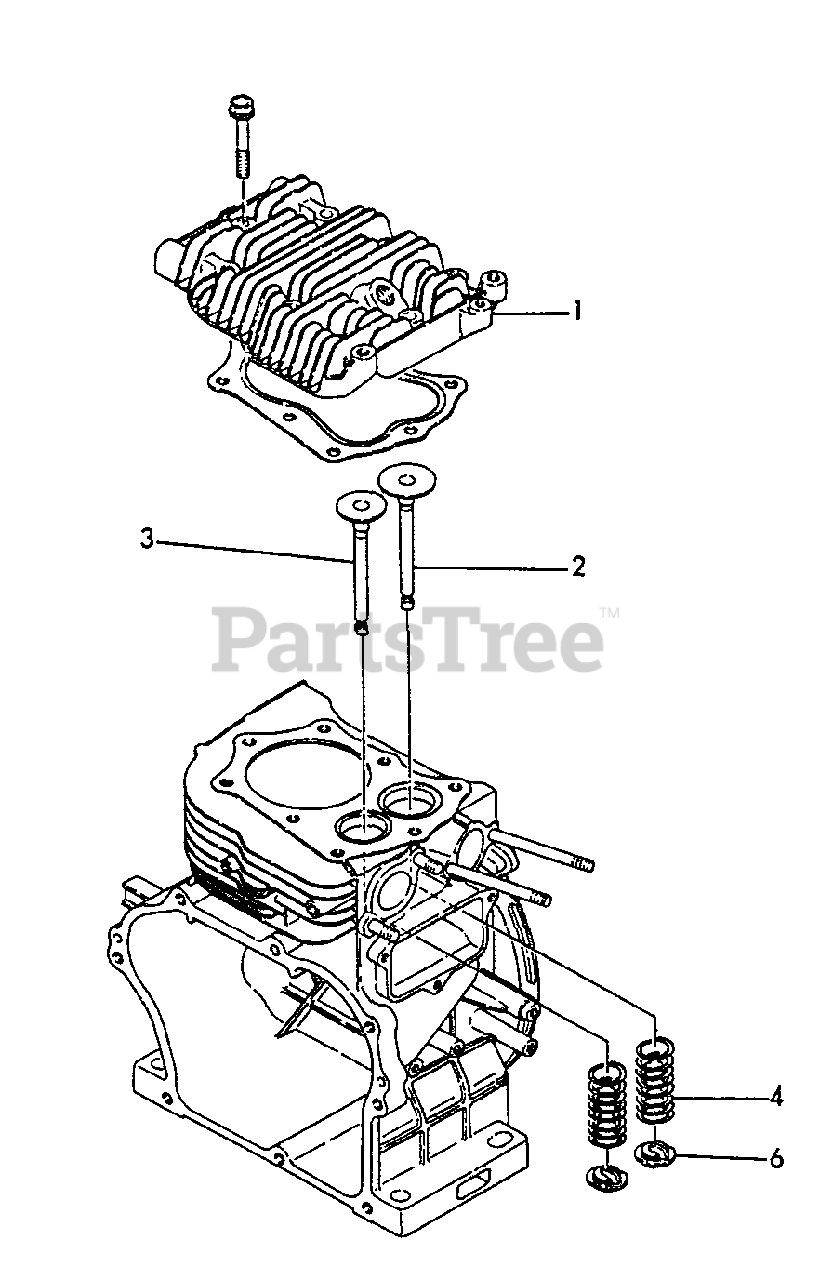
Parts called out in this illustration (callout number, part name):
1	HEAD, CYLINDER
2	VALVE, SUCTION
3	VALVE, EXHAUST
4	SPRING, VALVE
